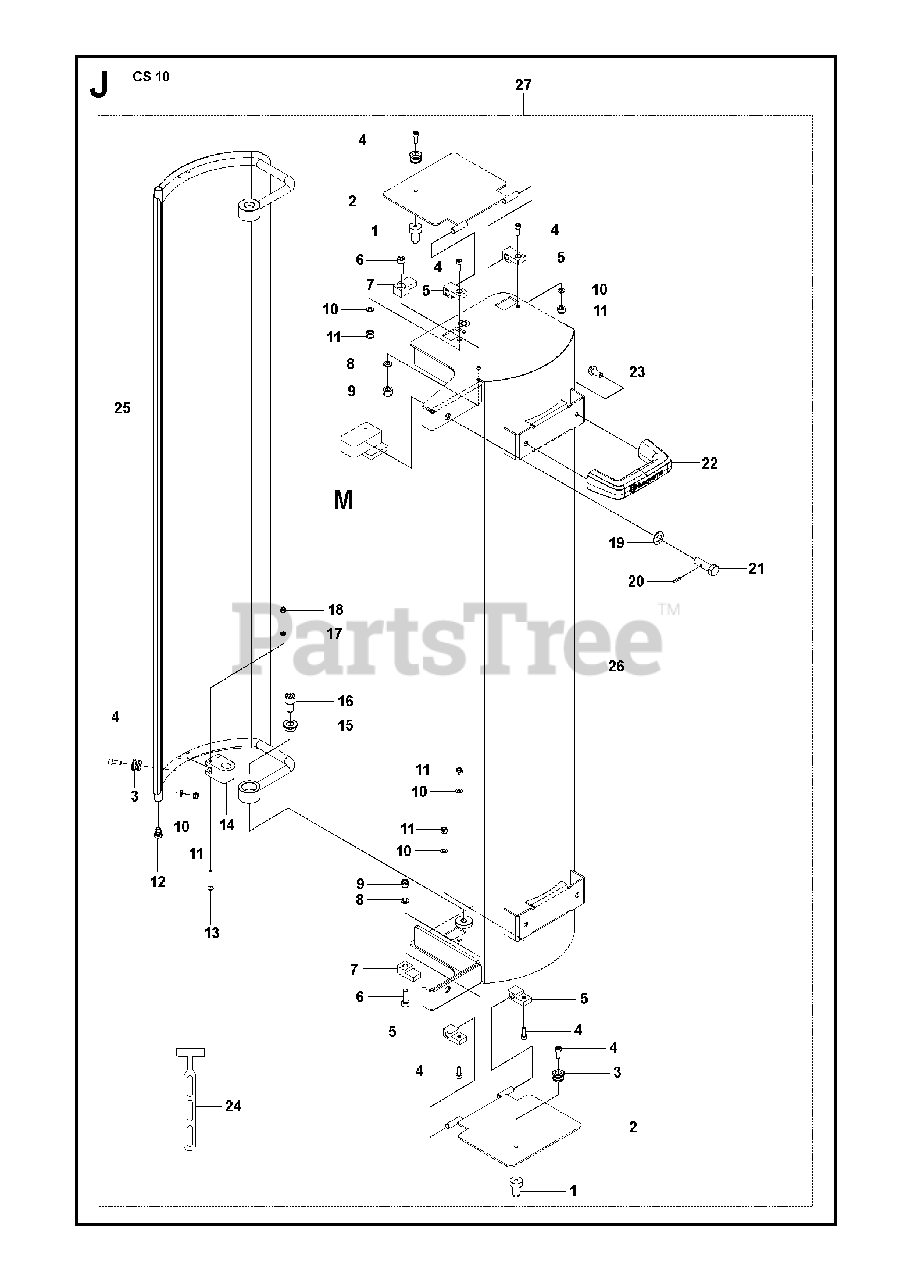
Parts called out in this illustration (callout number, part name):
8	WASHER
9	HEXAGON LOCKING NUT
11	HEXAGON LOCKING NUT
17	WASHER
18	HEXAGON LOCKING NUT
